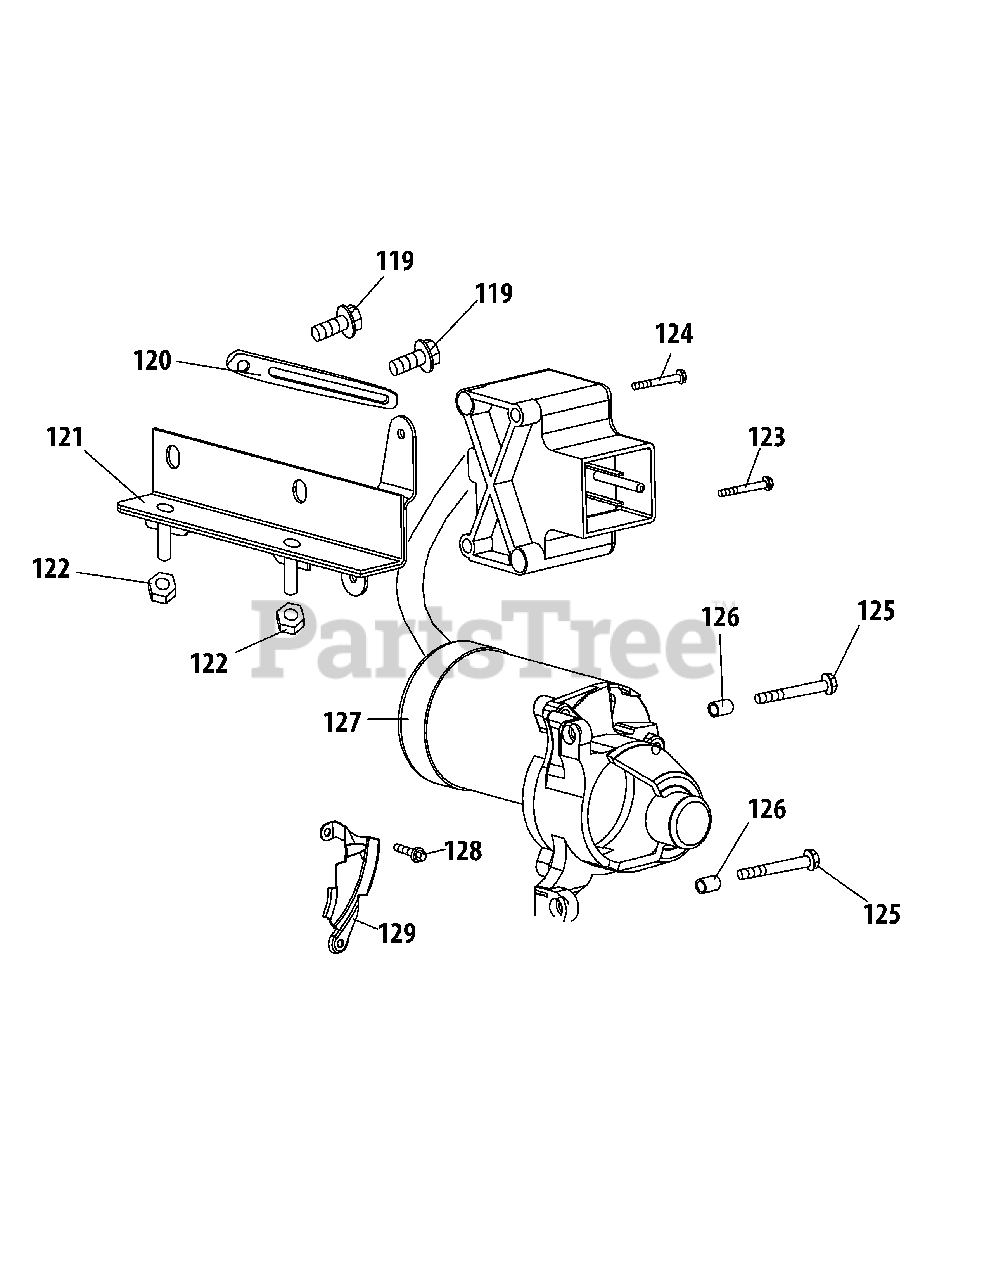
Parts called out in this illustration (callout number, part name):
119	Bolt M6×10
121	Switch Housing Mounting Bracket
123	Bolt M4×60
124	Bolt M4×55
125	Bolt M6×32
126	Dowel Pin 8×8
127	Electric Starter
128	Bolt M6×12
129	Blower Housing Shield
